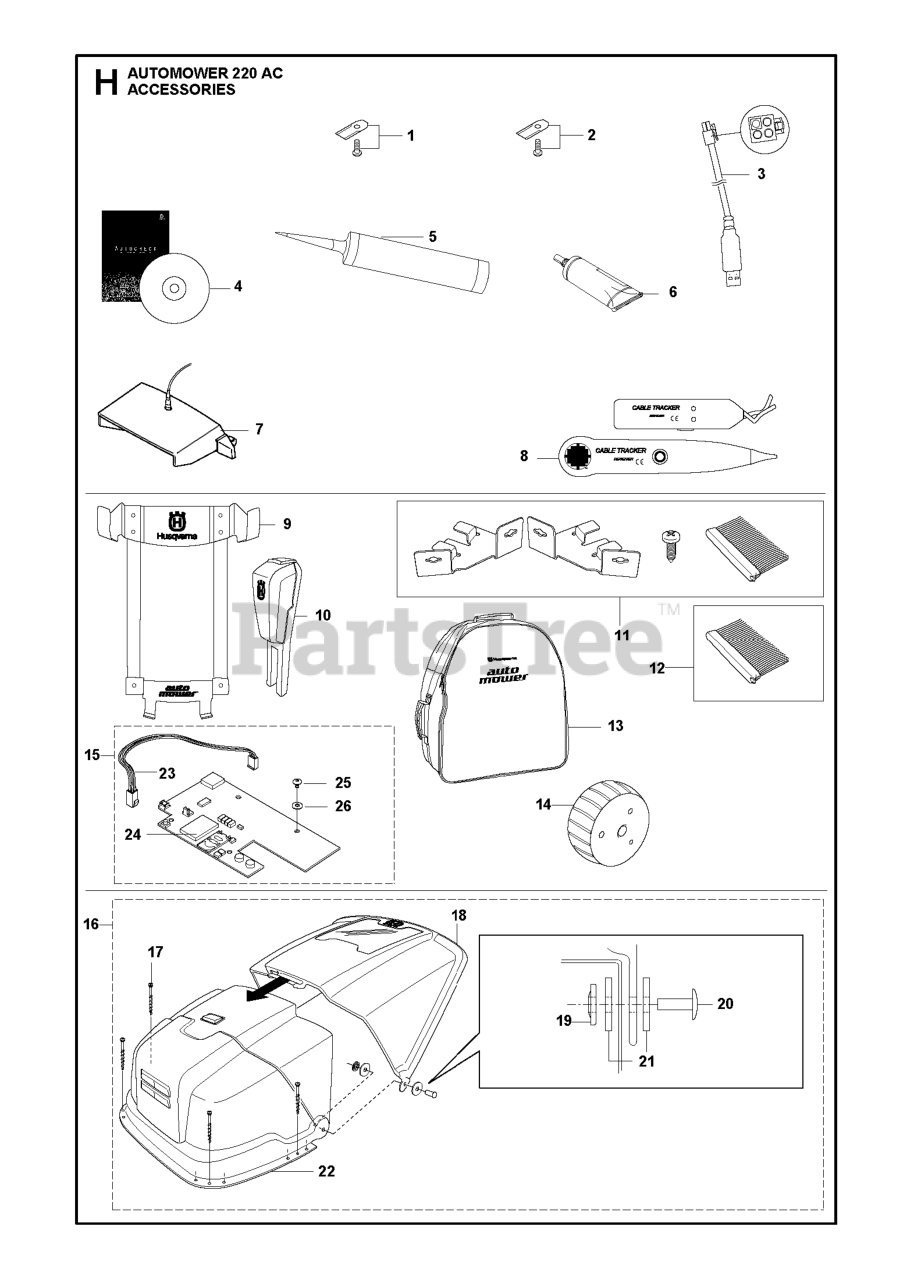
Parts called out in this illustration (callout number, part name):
1	BLADE 45PCS, CARBON
1	BLADE KIT
1	HUS 9 PC BLADE SET .35MM
1	BLADE - BULK PACK 500 PCS
2	BLADE 300PCS -SINGLE HOLE THIC
2	BLADE BLADE KIT INCL PACKAGING
2	BLADE 9 PCS EXTRA THICK
2	BLADE
3	USB SERVICE CABLE
5	GREASE 300 ML
6	SEALANT
6	GREASE OKS 110 85ML
7	N/A PIN CODE TRANSFER UNIT ADA
8	TEST EQUIPMENT
9	WALL BRACKET ASSY
10	SIGNAL BOOSTER
11	BRUSH KIT BRUSH X6, HOLDER X2,
11	BRUSH KIT
12	BRUSH KIT
14	WHEEL ASSY
14	HEAVY FRONT WHEEL KIT INCL PAC
16	AUTOMOWER SHELTER
17	SCREW KIT CS
18	TOP INCL LOGO & WINDOW CHARG
19	LOCK WASHER
20	AXLE CHARGING STATION COVER
22	FRONT CHARGING STATION COVER
23	LOOM LOOM GPS TRACKING MODULE
24	BATTERY GPS TRACKING COMMUNICA
25	SCREW GSM- MODULE
26	WASHER GSM- MODULE
